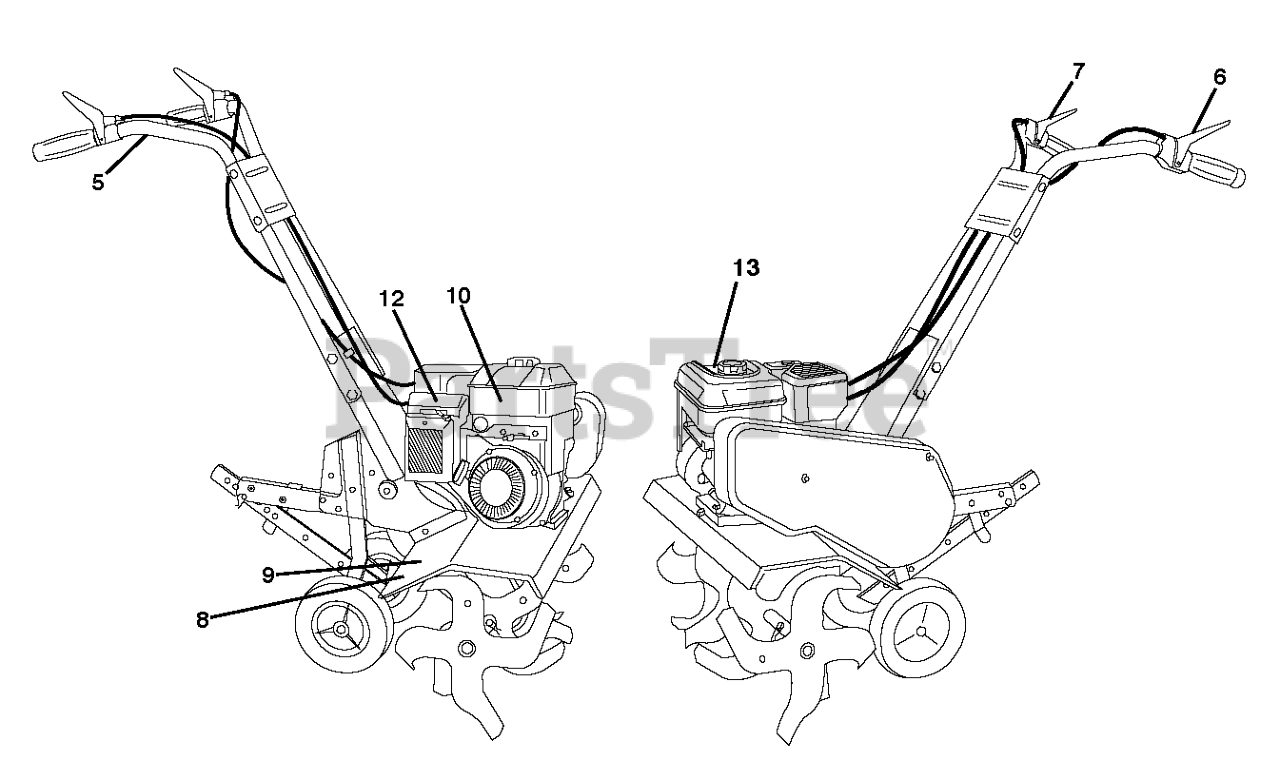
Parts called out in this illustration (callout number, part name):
5	DECAL TI (2 2)
6	DECAL
7	DECAL
8	DECAL TI
9	DECAL.WARNING.SHLD.ENG/FR
10	DECAL.B&S.900.TANK.REF.276991
12	DECAL.B&S.900.A/S.C (279005)
13	DECAL,ETHANOL E85 WARNING
